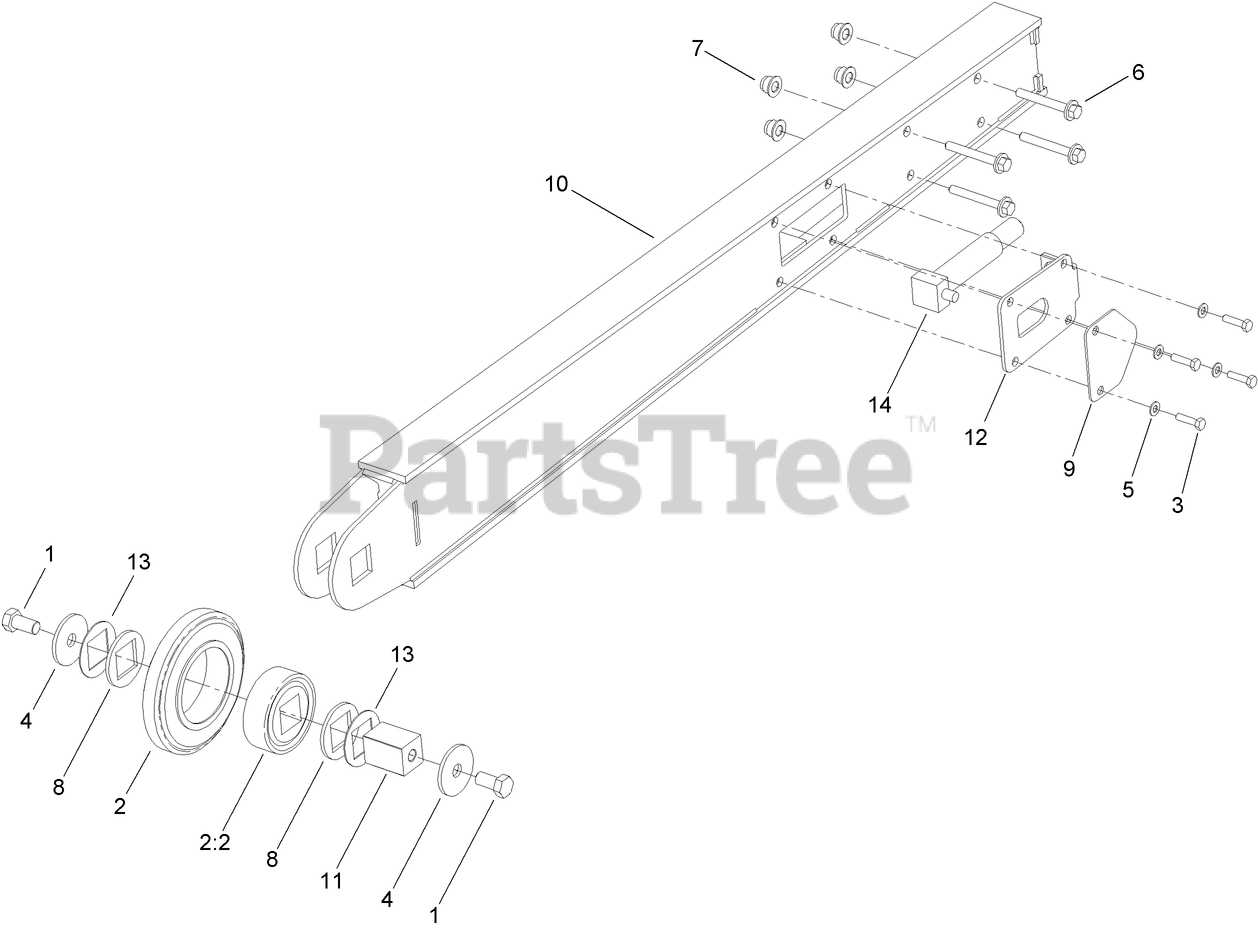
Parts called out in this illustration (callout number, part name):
1	SCREW-HH
2	IDLER ASM (BOOM END)
2:2	BEARING
3	SCREW-HH
5	WASHER-PLAIN
6	SCREW-HHF
7	NUT-HHF, LOCK
8	WASHER
9	PLATE-COVER
11	MOUNT-SHAFT, IDLER
12	PLATE-PISTON KEEPER
14	PISTON-ADJ
